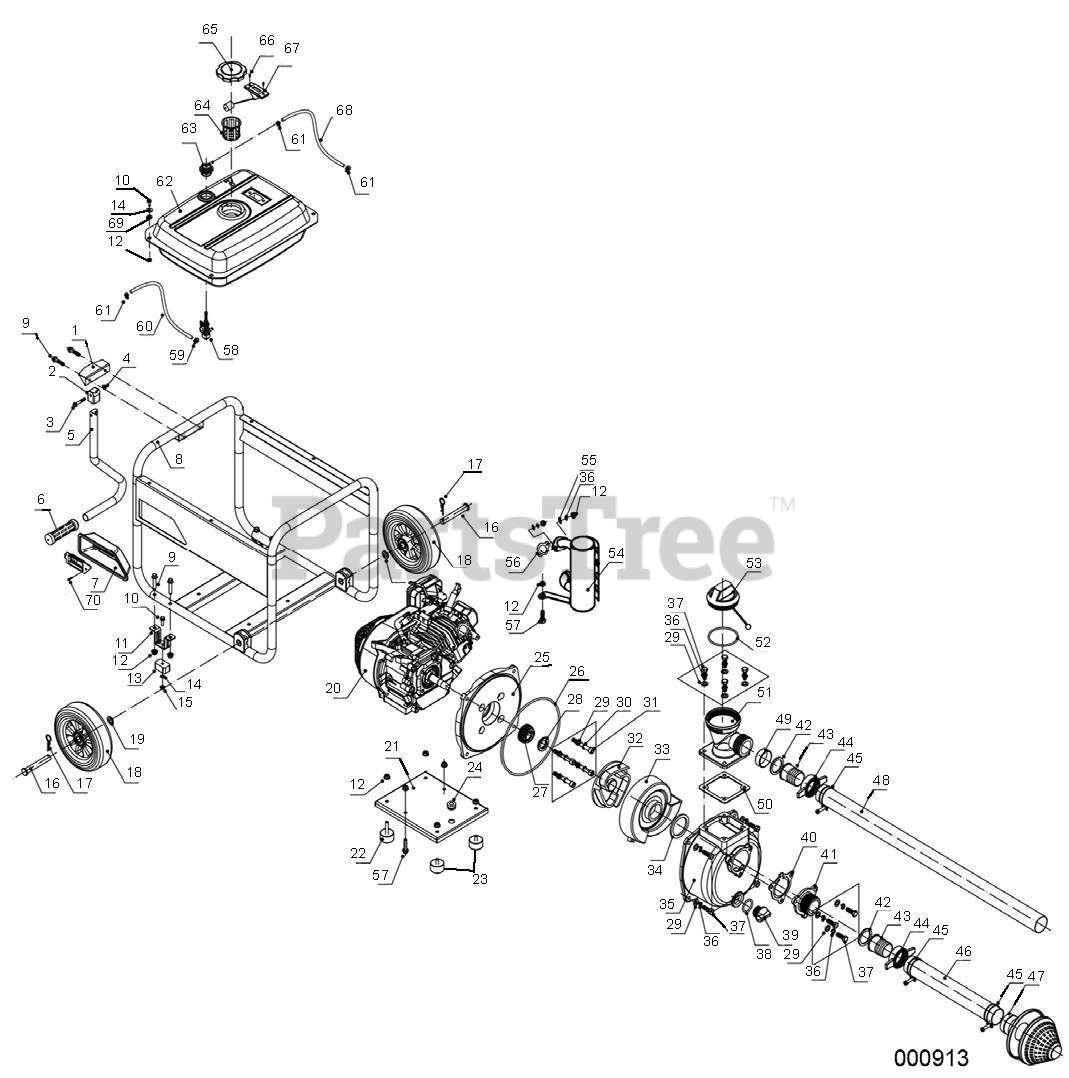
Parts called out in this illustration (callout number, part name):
1	HANDLE BRACKET
2	HANDLE SPACER
3	FLANGE BOLT (M6X40)
4	LOCKING NUT (M6)
5	HANDLE
6	HANDLE GRIP
7	PLASTIC RECOIL RECESS POCKET
8	FRAME FOR 2" WATER PUMP
9	FLANGE BOLT (M8X40)
10	FLANGE BOLT (M6X20)
11	BENT FOOT BRACKET
12	FLANGE NUT (M8)
13	RUBBER FOOT
14	FLAT WASHER
15	FLANGE NUT (M6)
16	AXLE FOR 2" WATER PUMP
17	COTTER PIN (6145)
18	WHEEL 8"
19	FLAT WASHER
20	ENGINE 208CC EPA3
21	BASE ASSEMBLY 2" WATER PUMP
22	SHOCK ABSORBER A
23	SHOCK ABSORBER B
24	SHOCK ABSORBER OF PUMP BODY
25	PUMP COVER
26	PUMP COVER O-RING
27	MECHANICAL SEAL (STATIONARY)
28	MECHANICAL SEAL (DYNAMIC)
29	FLAT WASHER
30	RUBBER WASHER
31	HEXAGON SOCKET CAP SCREW (M8X60)
32	WATER PUMP IMPELLER
33	VOLUTE CASING
34	O-TYPE SEAL RING
35	PUMP BODY (2" WATER PUMP)
36	SPRING WASHER
37	BOLT (M8X30)
38	PLUG SEAL RING
39	GENERAC 2" PLUG
40	ONE-WAY VALVE
41	SUCTION FLANGE 2"
42	SEALING RING
43	PIPE JOINT
44	JOINT GRIP
45	HOSE CLAMP
46	2" SUCTION HOSE-12 FEET LONG
47	SUCTION FILTER
48	2" DISCHARGE HOSE-25 FEET LONG
49	2" DISCHARGE FLANGE RUBBER RING(BLUE)
50	DISCHARGE ELBOW GASKET
51	2" DISCHARGE FLANGE
52	O-RING FOR GENERAC 2" PLUG
53	GENERAC 2" PLUG
54	MUFFLER
55	FLANGE BOLT WITH FLAT WASHER A (M8X25)
56	MUFFLER GASKET
57	FLANGE BOLT (M8X35)
58	FUEL SHUTOFF VALVE
59	HOSE CLAMP
60	FUEL HOSE (4.5X8.5) PREFORMED HOSE
61	HOSE CLAMP
62	FUEL TANK 11.5L
63	ROLL-OVER VALVE
64	FUEL TANK FILTER
65	FUEL CAP (BLACK)
66	SCREW (M5X14)
67	FUEL GAUGE
68	FUEL HOSE (4.5MM)
69	FUEL TANK SHOCK ABSORBER
70	CROSS SELF TAPPING SCREW
